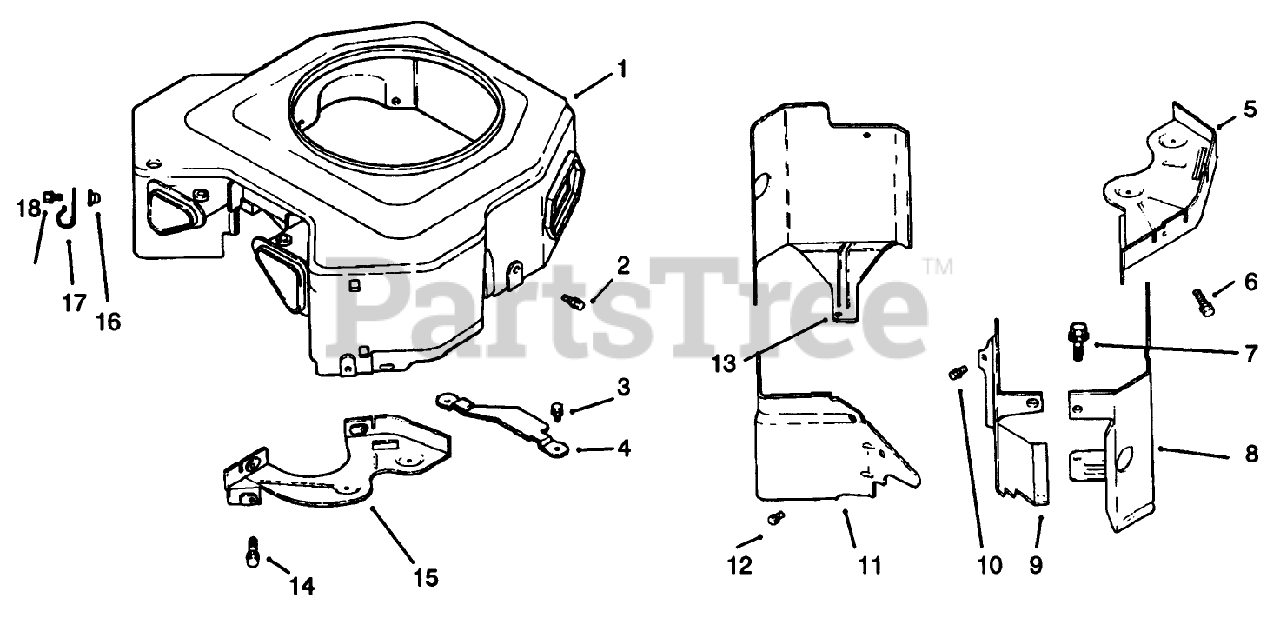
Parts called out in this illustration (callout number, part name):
1	Housing-Blower ASM (Only C)n: 72103, 72083)
4	Guard-Flywheel (Only On: 72103, 72083)
5	Plate-Backing #2 side
8	Baffle Cylinder #2 Side
9	Baffle-Valley #1 Side
11	Baffle-Valley #2 Side (Only On: 72103, 72083)
13	Baffle-Cyl. #1 Side
15	Plate-Backing #1
17	Clip-Cable (Only On: 72103)
